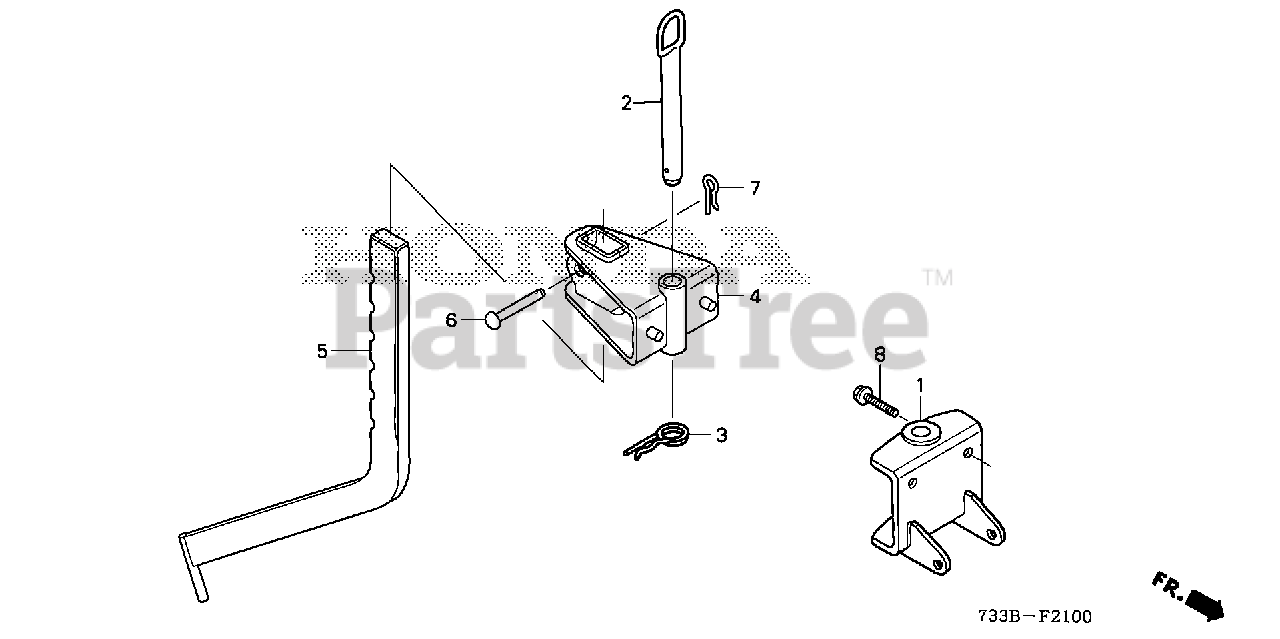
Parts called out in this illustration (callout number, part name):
1	BOX, HITCH
2	PIN, HITCH
3	PIN, LOCK
4	HITCH, ATTACHMENT
6	PIN (10X53.5)
7	PIN, LOCK (10MM) Use from Frame SN 2149606 to 2149605.
8	BOLT, FLANGE (8X25)
